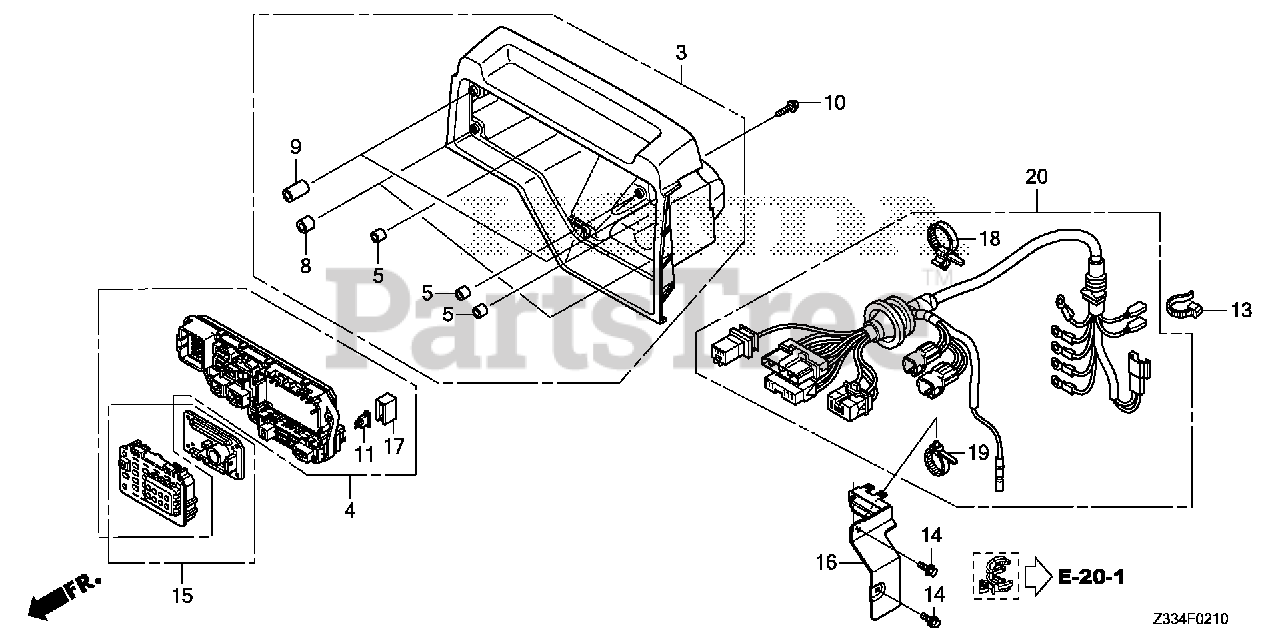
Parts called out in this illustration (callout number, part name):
3	CASE, CONTROL PANEL *NH314* (CONDUCT GRAY)
4	BOX ASSY., JUNCTION
5	COLLAR, BODY COVER
8	COLLAR, CONTROL CASE
9	COLLAR, CONTROL CASE
10	BOLT, FLANGE (6X20)
11	FUSE, BLADE (10A)
13	TIE, CABLE (C)
14	BOLT, FLANGE (6X12) (CT200)
15	COVER ASSY., AUTOMATIC VOLTAGE REGULATOR
16	BASE, HARNESS CLIP
17	COVER, FUSE
18	CABLE, STRAP
19	CLIP, HARNESS BAND (145MM) (BLACK)
20	WIRE HARNESS ASSY., GENERATOR
